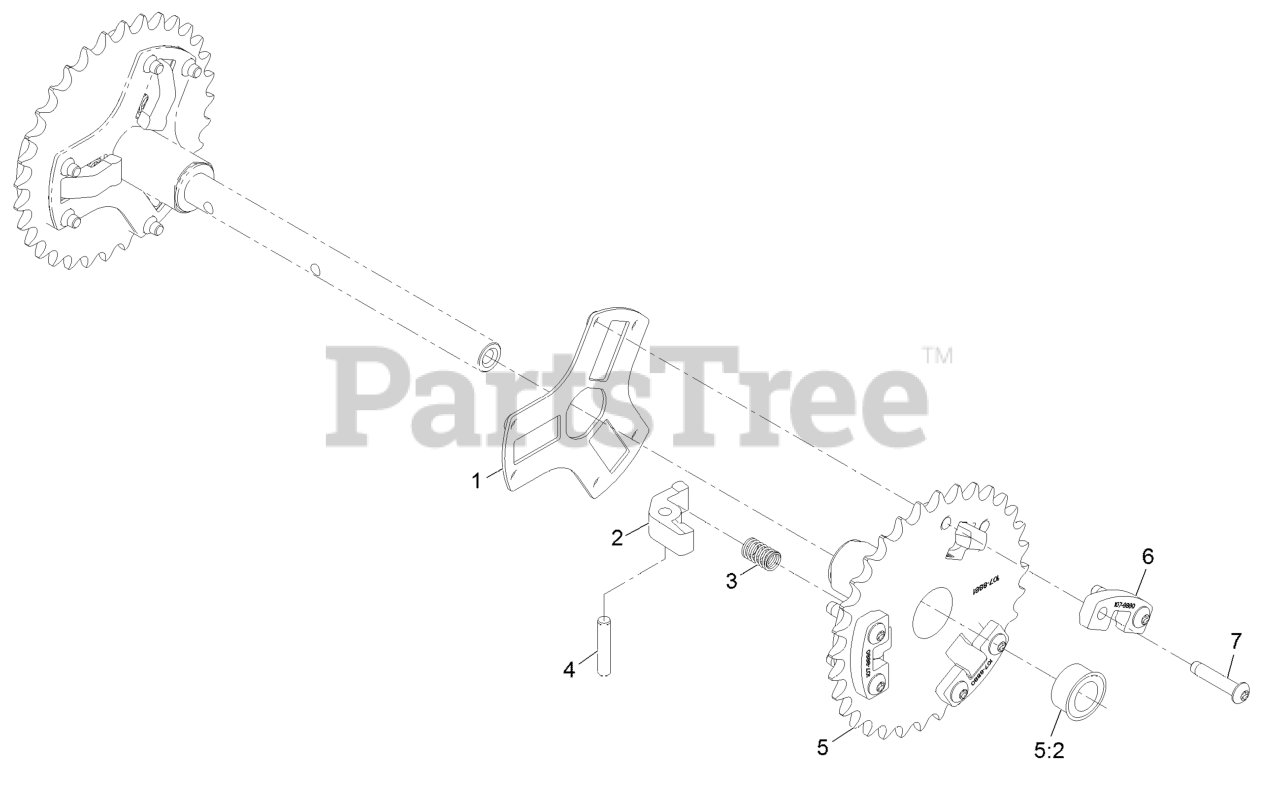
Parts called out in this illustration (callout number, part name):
1	RETAINER-PIN, PAWL
2	PAWL-CLUTCH
3	SPRING-COMPRESSION
4	PIN-DOWEL
5	32T SPROCKET ASM
5:2	BUSHING-FLANGE
6	SUPPORT-PAWL
7	SCREW-TTH, THREAD ROLLING
